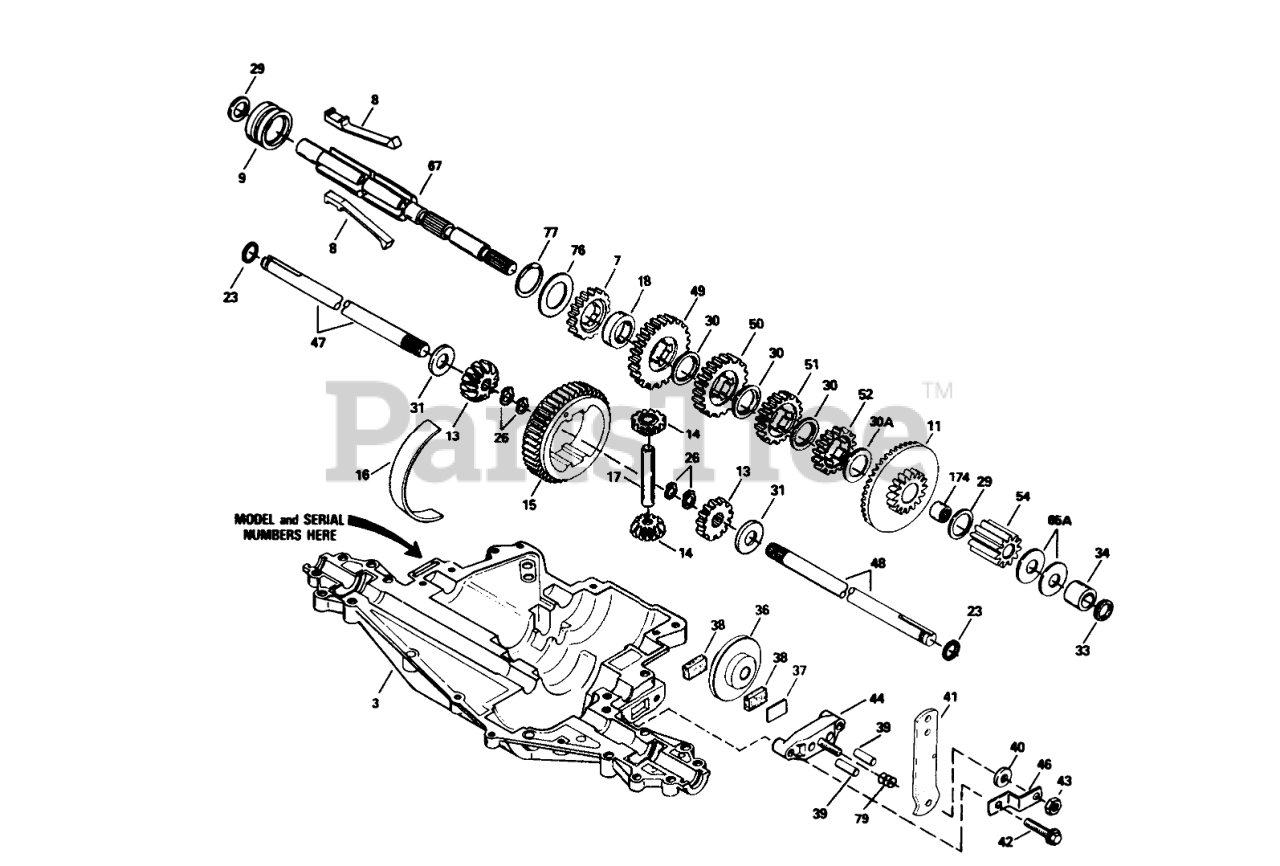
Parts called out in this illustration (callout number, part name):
3	Transaxle Case
7	Gear-Spur (22 teeth)
8	Shift Key
9	Shift Collar
11	Bevel Gear & Bearing (44/16 Teeth) (Incl. Ref. #174)
13	Gear Bevel
14	Gear Pinion
15	Gear-Ring
16	Bearing Strip
17	Drive Pin
18	Neutral Spacer
23	Ring-Seal
26	Retaining Ring (pkg of 2)
29	Washer
30	Washer
30A	Washer
31	Washer
33	O-Ring
34	Bushing
36	Brake Disk
37	Brake Pad Plate
38	Brake Pad
39	Dowel Pin
40	Washer
41	Brake Lever
42	Ring Set (.020 O S)
43	Locknut
44	Nozzle-Carburetor
46	Bracket
47	Axle (16-13/16" Ig.)
48	Axle (11-5/8" Lg.) (Incl. Ref. #26)
49	Gear-Spur, 35 Teeth
50	Gear-Spur 27 Teeth
51	Spur Gear (19 Teeth)
52	Gear-Spur 20 teeth
54	Spur Gear (11 Teeth)
65A	Washer
67	Shifter & Brake Shaft
76	Washer
77	Inverted Retaining Ring
79	Piston ASM (.020 O S)
174	Needle Bearing
